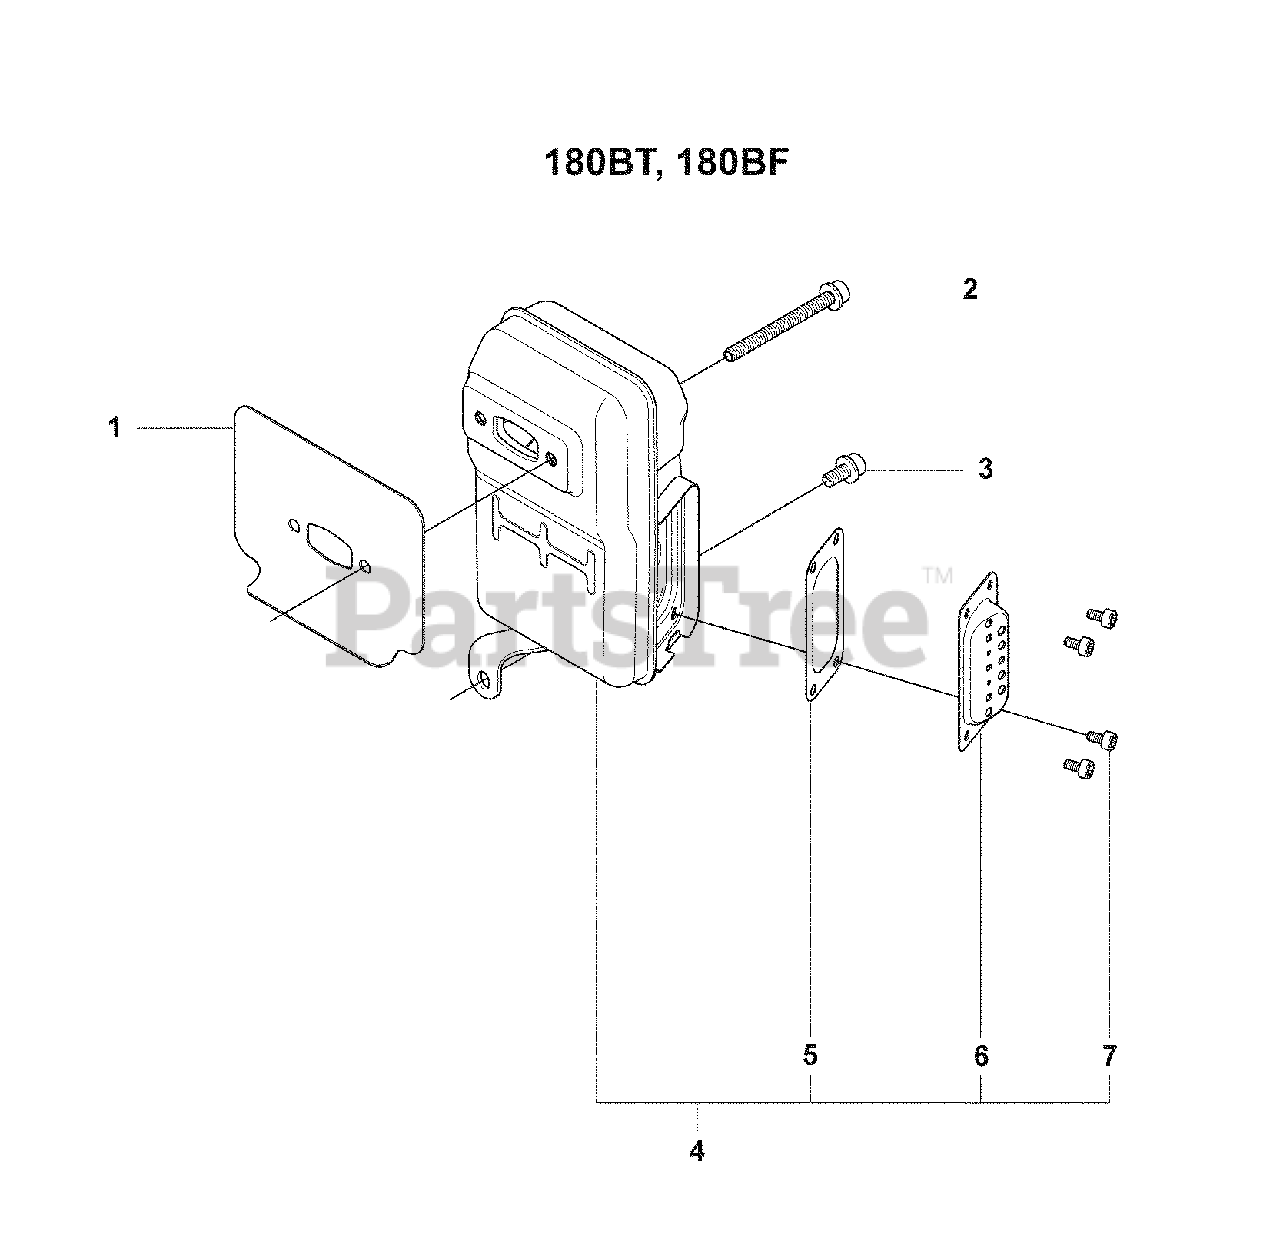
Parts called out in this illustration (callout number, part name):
3	Bolt
4	Muffler Assembly
6	RP_DIFFUSER
